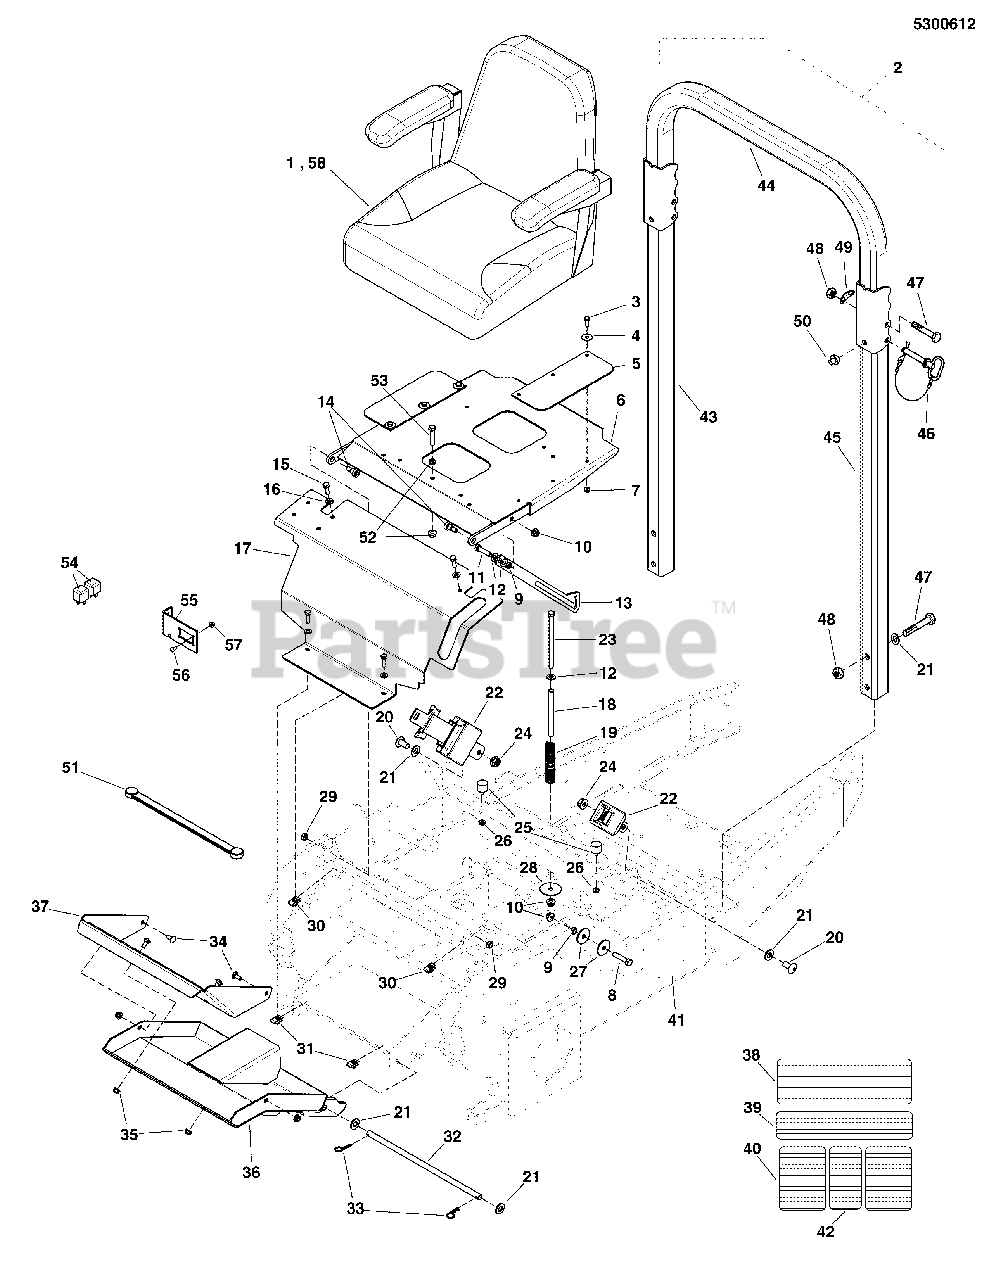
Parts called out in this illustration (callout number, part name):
1	SEAT, 2012
2	ROPS (Call 1-800-933-6175 x708 if replacing a ROPS)
3	BOLT, 1/4-20 X 3/4 GD5 YZ
4	WASHER, 1/4 FENDER
5	PLATE, SEAT, RUBBER FLAP
6	WELD, SEAT MOUNT - RED
7	NUT, 1/4-20 HEX NYLOCK FLANGE
8	BOLT, 3/8-16 X 1-3/4 GD5
9	NUT, 3/8-16 HEX JAM
10	NUT, 3/8-16 HEX NYLOCK FLANGE
11	BOLT, 3/8-16 X 1-1/2 GD5 YZ
12	WASHER, 3/8 SAE
13	BAR, SEAT PROP - RED
14	BOLT, 3/8-16 X 3/8, 1/2 SHOULDER
15	BOLT, 5/16-18 X 1 GD5 YZ
16	WASHER, 5/16 SAE
17	PLATE, FRONT COVER - RED
18	SPACER, .38 X .50 X 5.06
19	SPRING, COMP, .835 X.105 X4.26
20	SCREW, 1/2-13 X 1.00, SHCS
21	WASHER, 1/2 SAE
22	SEAT BELT, RETRACTING - ASSM
23	BOLT, 3/8-16 X 6 GD5 YZ
24	NUT, 1/2-13 HEX NYLOCK FLANGE
25	MNT, VBRTN, RBBR
26	NUT, 1/4-20 HEX SERR. FLANGE
27	WASHER, .390 X 1.50 X .109, YZ
28	WASHER, .39 X 2.00 X X .14
29	NUT, 3/8-16 HEX SIDE LOCK
30	BODY CLIP, 5/16-18 -1/4 MATERIAL
31	BODY CLIP, 5/16-18-7GA MATERIAL
32	ROD, HINGE, 1/2 X 14.25, YZ
33	PIN, HAIR, .0915 X 1-7/8
34	BOLT, 5/16-18 X 3/4, CARRIAGE
35	NUT, 5/16-18 HEX NYLOCK FLANGE
36	WELD, FLOOR PLATE - RED
37	PLATE, UPPER FLOOR
38	SAFETY WALK, 5.13 X 15.25
39	SAFETY WALK, 3.13 X 15.5
40	SAFETY WALK, 7.25 X 5.25
41	WELD, MAIN FRAME, S800X - RED
42	SAFETY WALK, 7.13 X 3.63
43	ROLL BAR POST, RH
44	ROLL BAR, TOP LOOP
45	ROLL BAR POST, LH
46	PIN, HITCH, .50 X 3.25 W/ LAY
47	BOLT, 1/2-13 X 3-1/2, ALLEN HEAD, YZ
48	NUT, 1/2-13 HEX SIDE LOCK
49	LANYARD HOLDER
50	BUMPER, ROPS
51	STRAP-BLACK RUBB
52	NUT, 3/8-16 HEX SERRATED FLANGE
53	BOLT, 3/8-16 X 2 GD5 CZ
54	RELAY, 12V, 40A
55	BRACKET, RELAY MOUNT
56	SCREW,#8-32 X 5/8 PHILLIPS, PAN HEAD, ZP
57	NUT, #8-32 HEX NYLON LOCK
58	SEAT, CI3, SEAT'S INC. 2016
